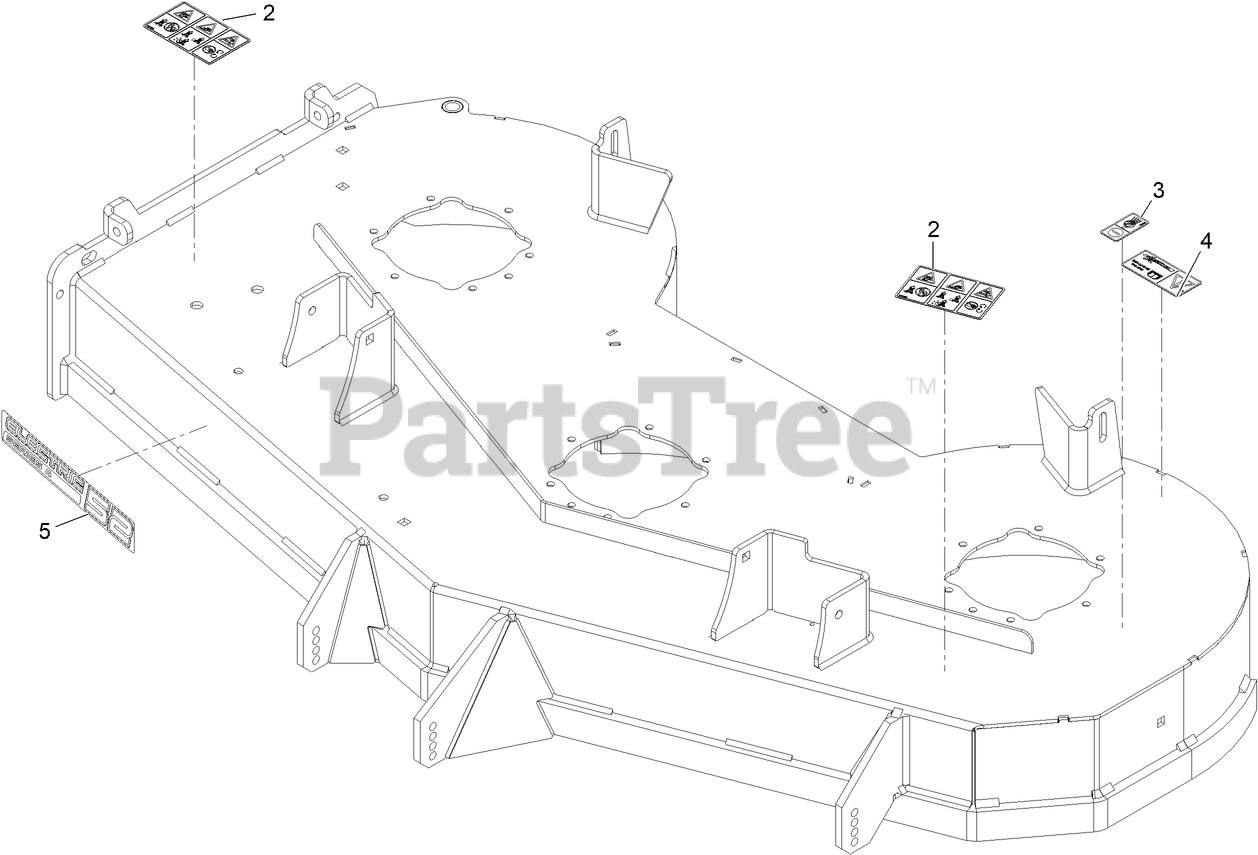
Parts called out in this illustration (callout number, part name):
2	DECAL-DANGER, CE
3	DECAL-NO SPRAY
4	DECAL-DANGER
5	DECAL-ELECTRIC 52-SERIES 4
